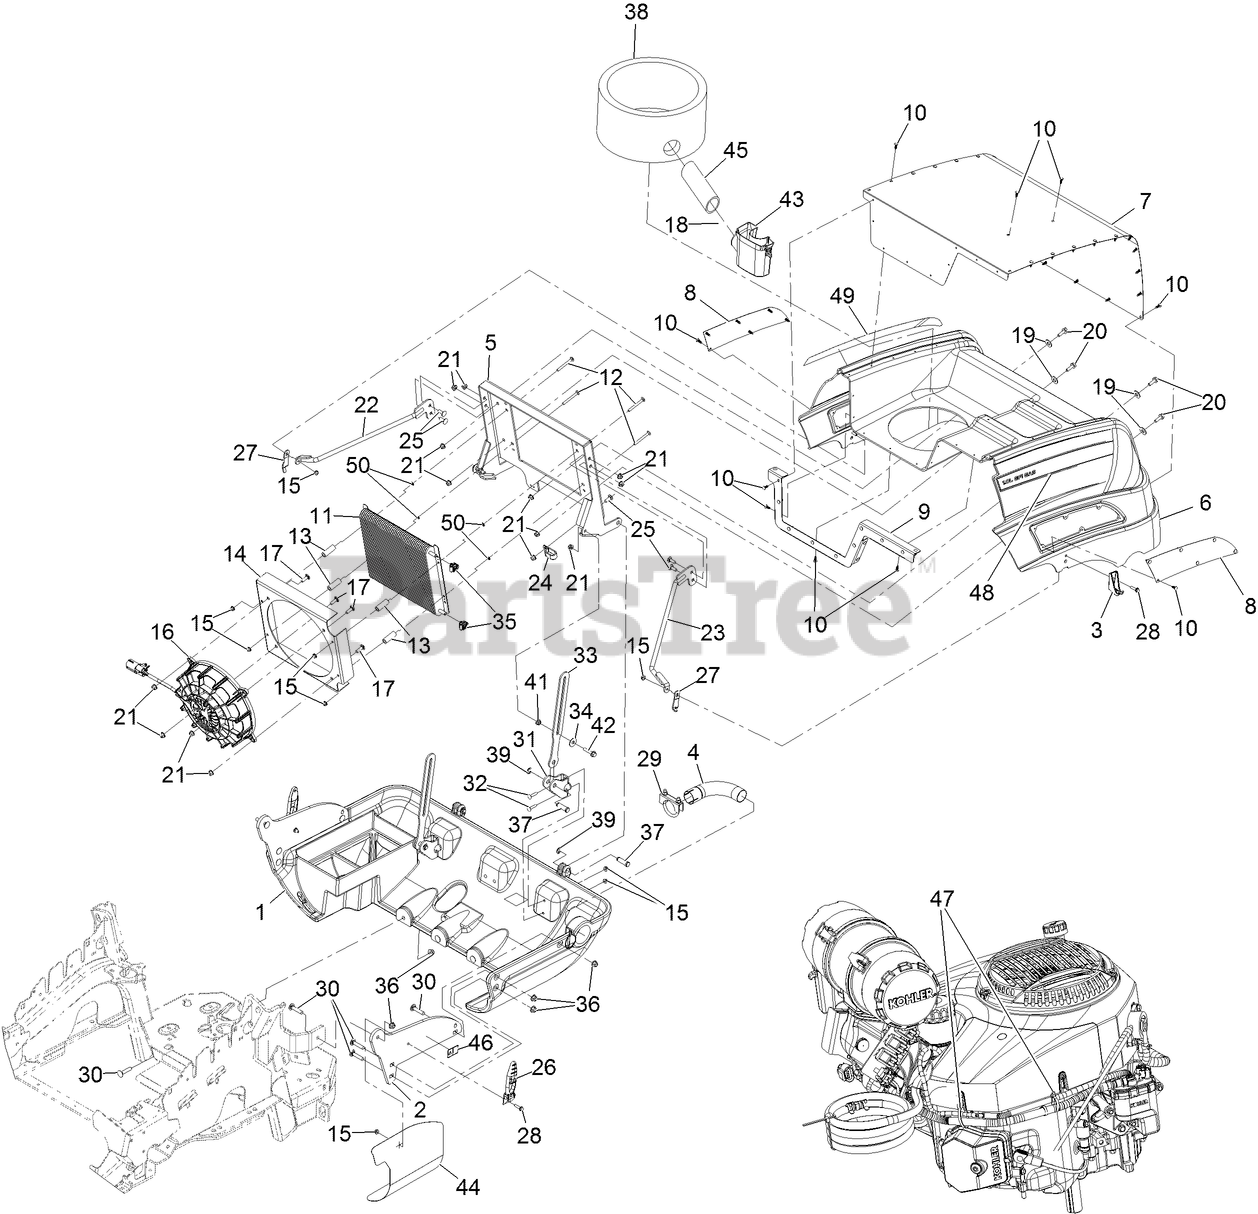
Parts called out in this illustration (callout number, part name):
1	Casting-Lower, Rear
2	Plate-Mount
3	LATCH-CATCH
4	Tube-Exhaust
5	Mount-Cooler
6	HOOD-EXMARK-GRAY
7	Screen-Intake
8	Screen-Intake
9	Cap-Perforation, Hood
10	Plug-Plastic
11	Cooler-Oil
12	SCREW-CARR
14	Mount-Fan
17	SCREW-CARR
19	WASHER-FLAT
20	SCREW-HHF
21	NUT-HF, NI
22	Support-Hood, RH
23	Support-Hood, LH
25	BOLT-CARR
26	LATCH-RUBBER
27	Stop-Hood
28	SCREW-HHF
30	SCREW-CARR
31	Bracket-Mount, Slide
32	SCREW-CARR
33	Slide-Hood
34	WASHER-PLASTIC
35	Clamp-Hose
36	NUT-HF, NI
38	Foam-Inlet, Air
39	RING-RETAINING, EXTERNAL
42	SCREW-HHF
43	Mount-Hose
44	Barrier-Heat
45	Hose-Air Intake
46	DECAL-WARNING
47	TIE-CABLE
48	DECAL-LH STRIPE
49	DECAL-RH STRIPE
50	Nut-Push
